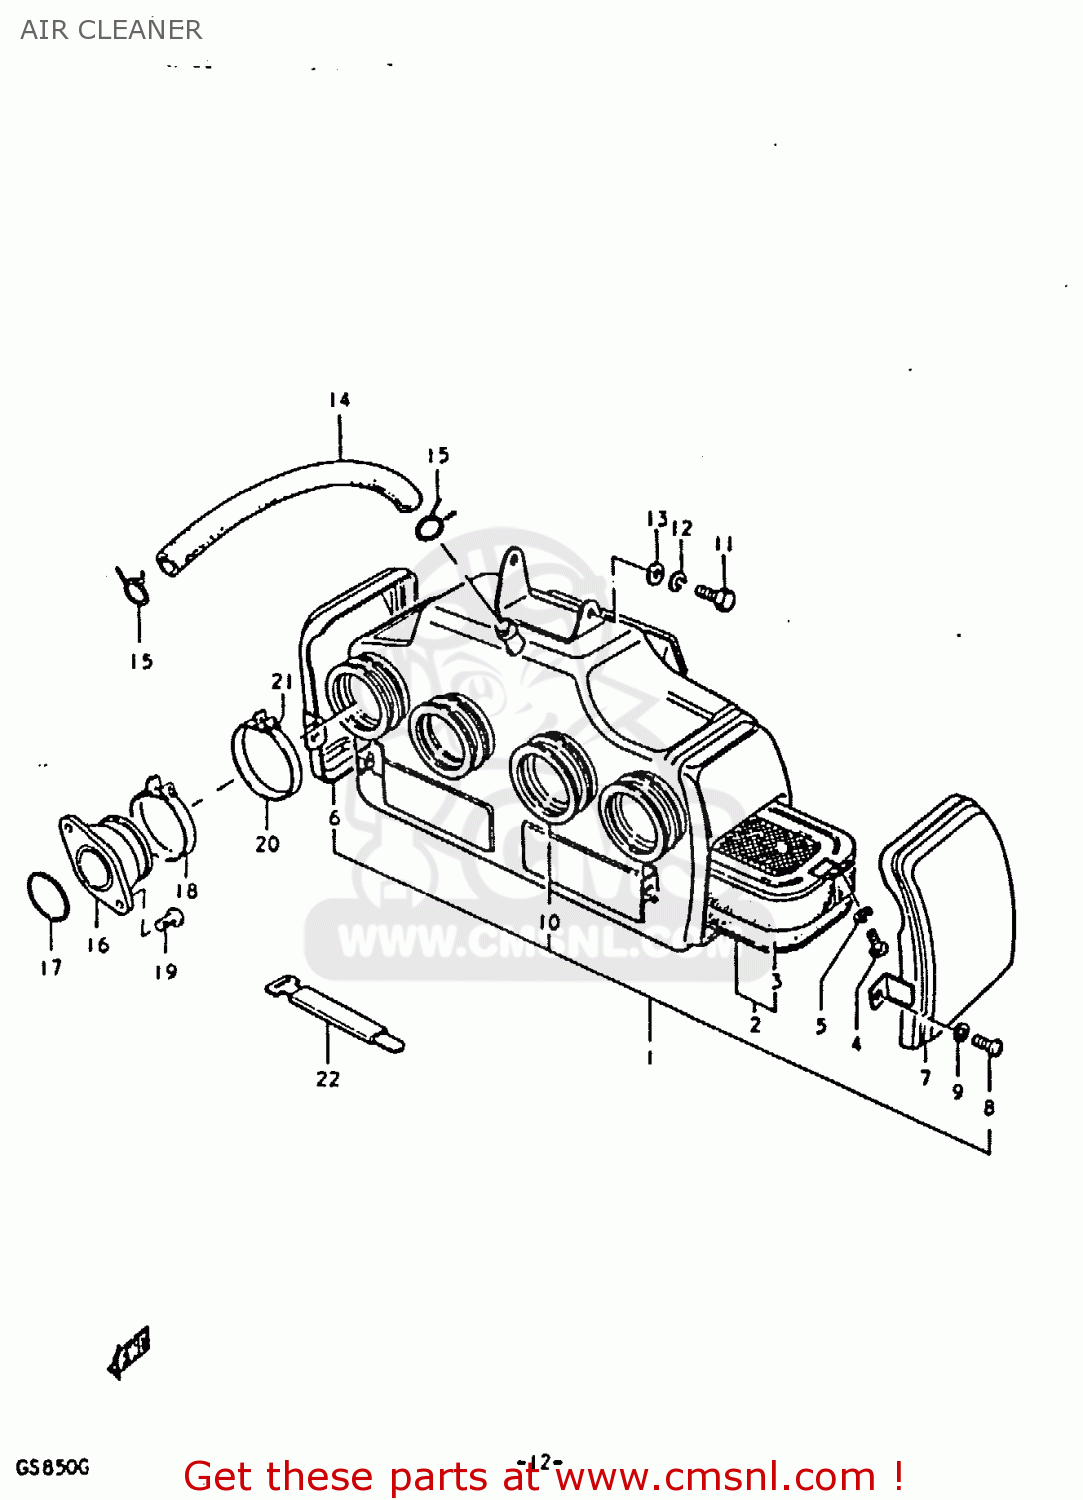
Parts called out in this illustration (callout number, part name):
1	CLEANER ASSEMBLY,AIR
2	FILTER ASSY,AIR CLEANER
3	FILTER
4	SCREW
5	LOCK WASHER
6	CAP,AIR CLEANER
7	COVER,AIR CLEANER,LEFT
8	SCREW
9	LOCK WASHER
10	HOSE
11	BOLT
12	LOCK WASHER
13	WASHER
14	HOSE
15	CLIP
16	PIPE,INTAKE
17	O RING(D:2.4,ID:31.7)
18	CLAMP
19	SCREW
20	CLAMP
21	SCREW TAPP.
22	CLAMP(L:120)
